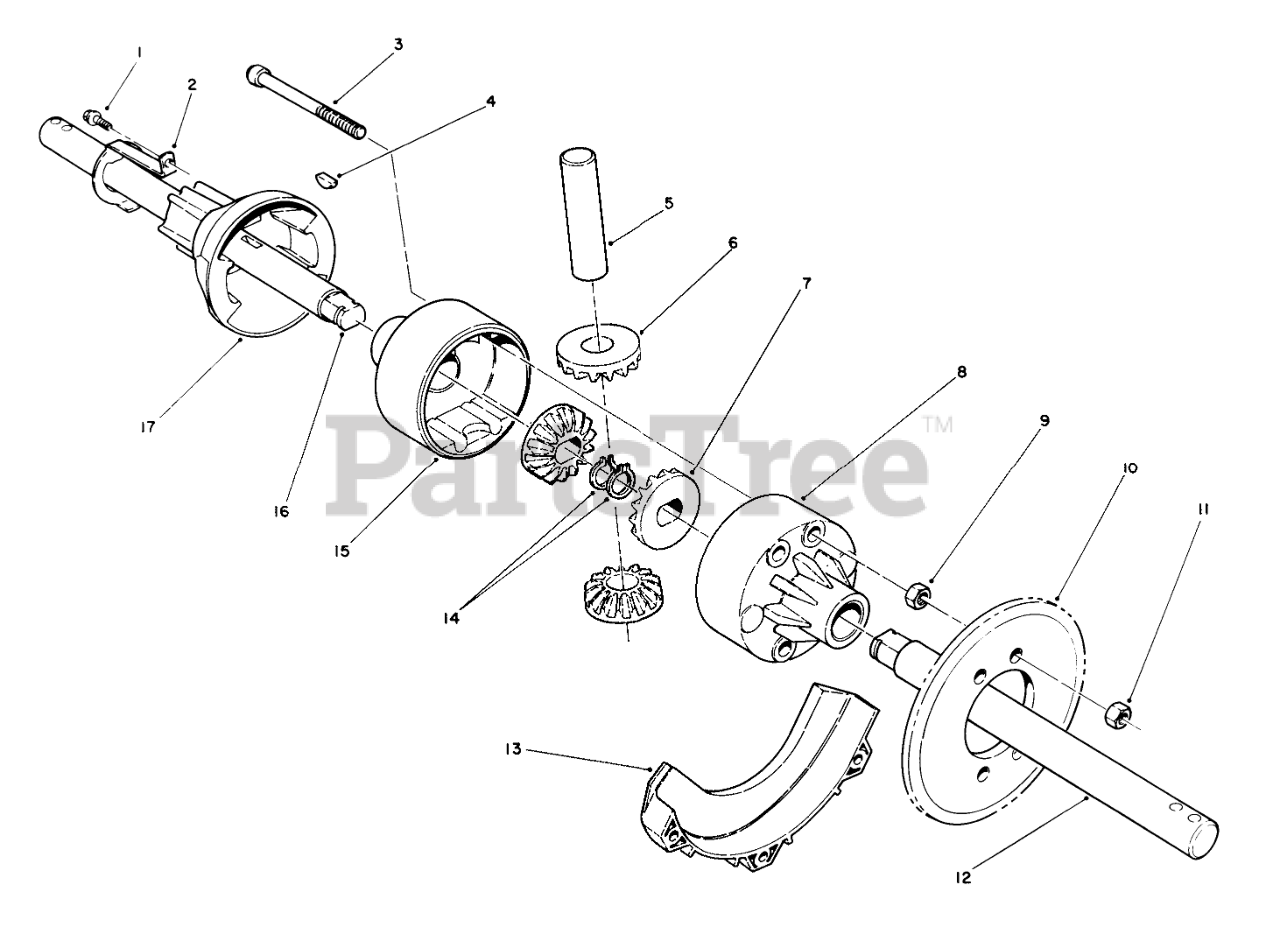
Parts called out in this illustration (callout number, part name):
1	SCREW-HWH
2	SPRING-LOCKOUT
3	SCREW-HSH
4	KEY-WOODRUFF
5	Shaft-Cross
6	Gear-Cross Shaft Pinion
7	Gear-Side Pinion
8	HOUSING ASSY - FEMALE
9	NUT-HEX
10	SPROCKET-27T
11	NUT-LOCK, NI
12	SHAFT - DIFFERENTIAL,LH
13	GUARD-CHAIN
14	RING-RETAINING
15	HOUSING ASSY - MALE
16	SHAFT - DIFFERENTIAL,RH
17	COUPLING-DIFFERENTIAL
